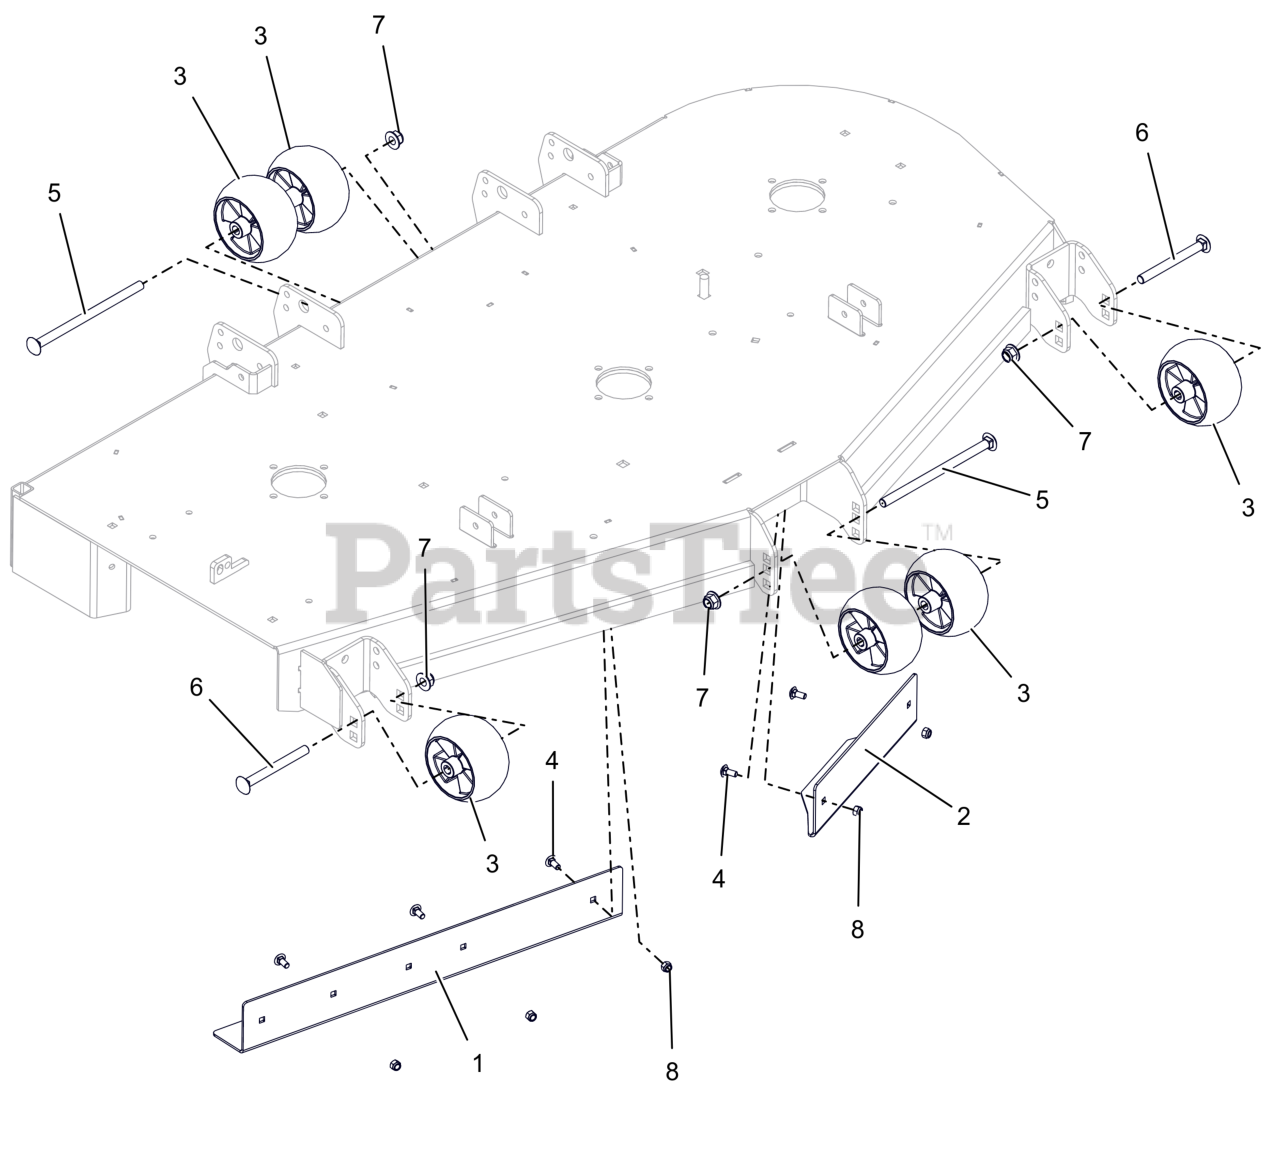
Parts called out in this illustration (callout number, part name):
1	BAFFLE, 60" RH VACUUM (RED)
2	BAFFLE, 60" LH VACUUM (RED)
3	WHEEL, ANTI SCALP - 5X3 CTR W/RIBS
4	BLT,RHSN .31-18X.75 G5 ZCC
5	BTL,RHSN .500-13 X 8.5S G5 ZCC
6	BLT, RHSN .50-13X5.00 G5 ZCC
7	NUT,NYL-FLG .50-13 GF ZCC
8	NUT,NYL .31-18 G5 ZCC
